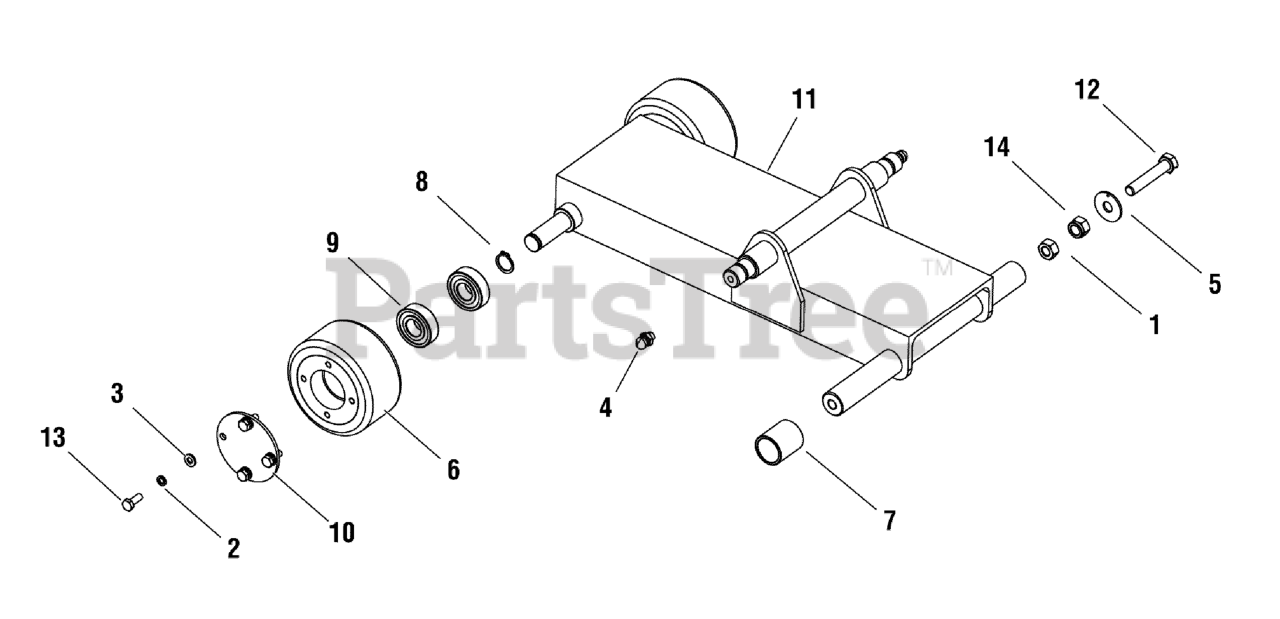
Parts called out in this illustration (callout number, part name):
1	NUT, Hex, M10
2	WASHER, Spring
3	WASHER, Flat
4	NOZZLE, Grease
5	WASHER, Flat
6	WHEEL, Front
7	BUSHING
8	CIRCLIP
9	BEARING
10	COVER, Dustproof
11	FRAME, Wheel
12	BOLT, Hex, M10 x 55
13	BOLT, Hex, M6 x 16
14	NUT, Hex, Prevailing Torque, M10
